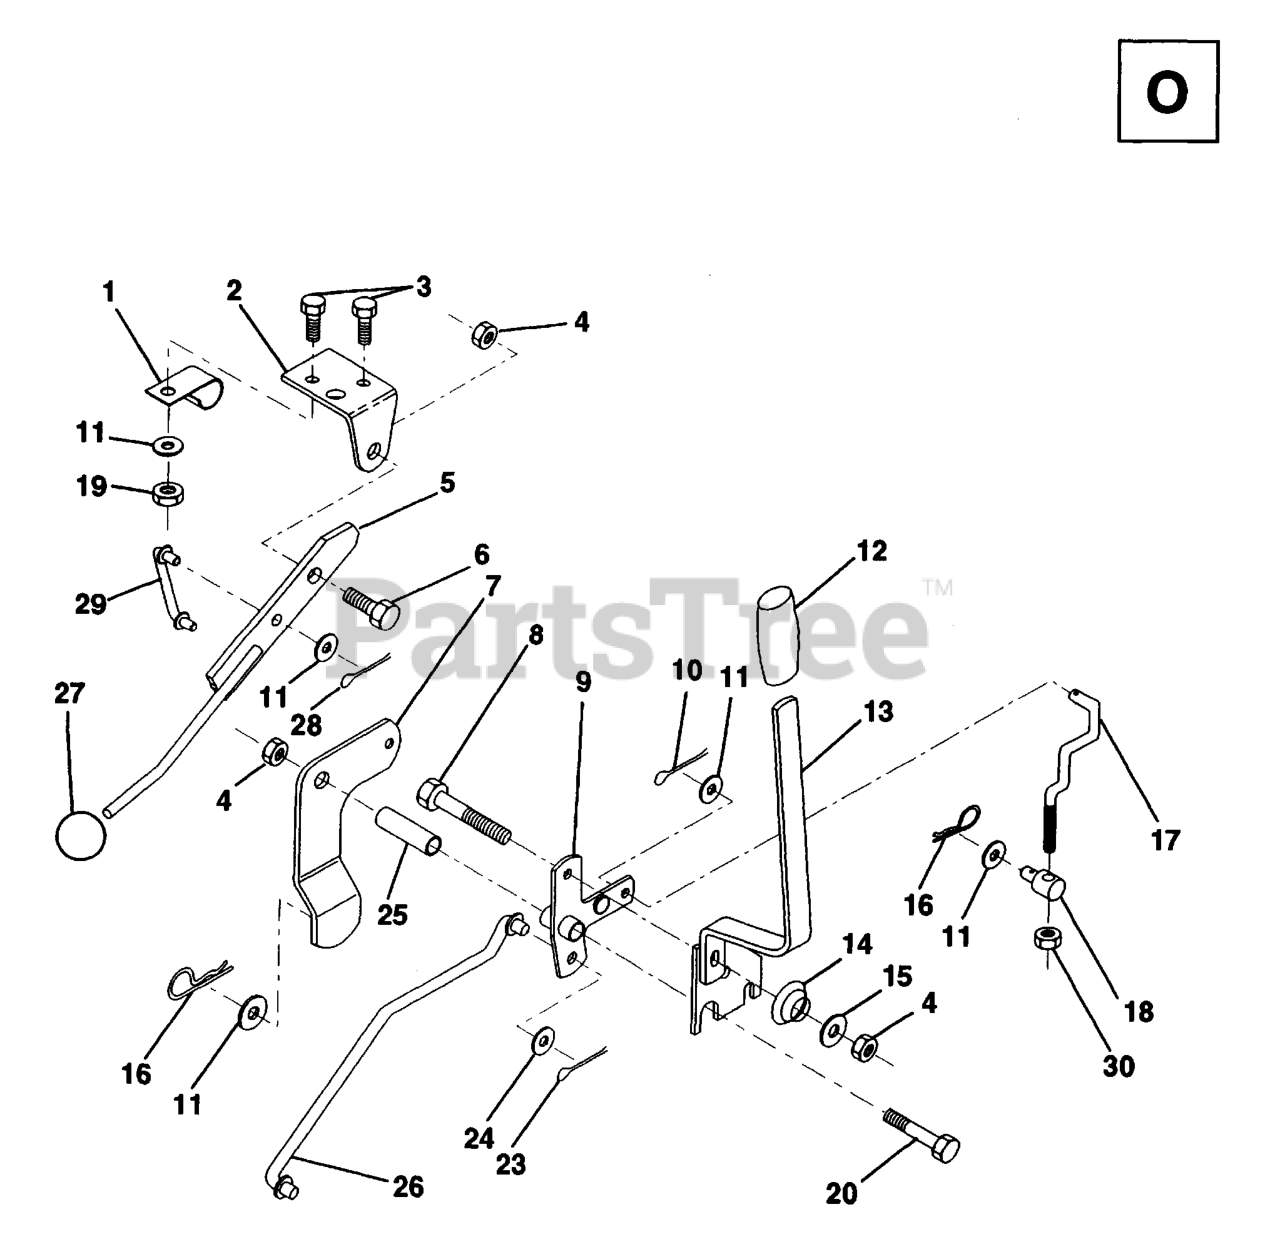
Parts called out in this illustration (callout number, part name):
1	CLIP,INSULATOR
2	BRKT CLUTCH
3	BOLT
4	NUT
5	CLUTCH LEVER ASSY
6	BOLT, SHOULDER LT
7	ASSEMBLY MOWER CLUTCH ARM
9	BELLCRANK,LIFT
10	COTTER PIN
11	WASHER
12	GRIP HANDLE
12	HANDLE GRIP
13	LIFT HANDLE ASSY
14	SPRING COMPRESSIO
15	WASHER T
16	COTTER PIN
17	LINK LIFT FRT
18	TRUNION
19	NUT.CROWNLOCK.1/4
23	PIN COTTER
24	WASHER
25	TUBE SPACER
26	ROD,MOWER LIFT
27	KNOB T (3/8 HOLE)
28	COTTER PIN
29	LINK MOWER CLUTCH
30	NUT
